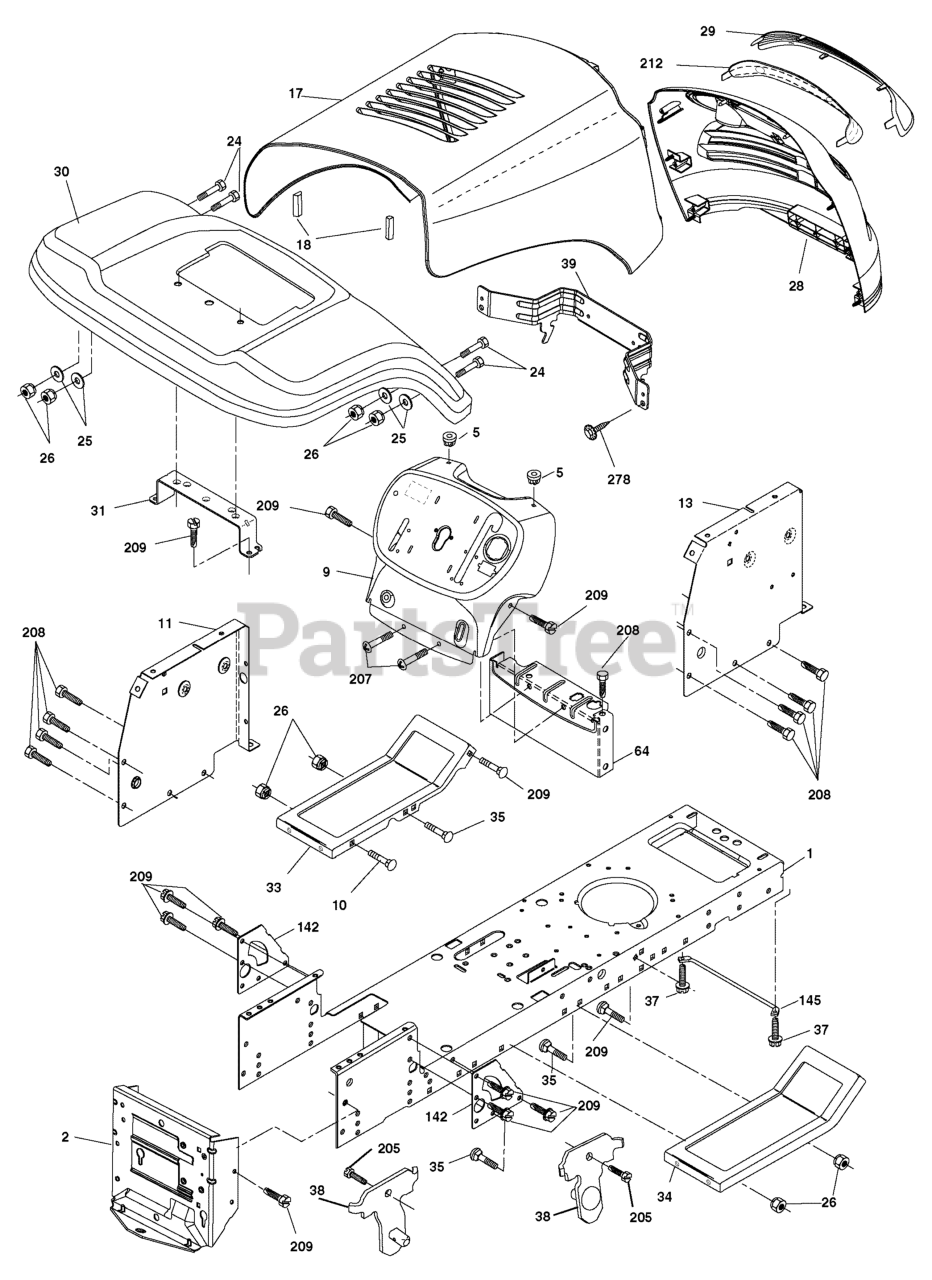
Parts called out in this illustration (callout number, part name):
1	CHASSIS
2	DRAWBAR
5	BUMPER, Hood / Dash
10	BOLT, Carriage, 3/8-16 x 1
11	PANEL, Dash, L.H.
13	PANEL, Dash, R.H.
17	** HOOD ASSEMBLY
18	BUMPER, Hood Large 1.75
24	BOLT, Fin Hex 3/8-16 unc x 1 Gr. 5
25	WASHER, 13/32 x 13/16 x 12 Ga.
28	** GRILLE
30	** FENDER
31	BRACKET, Fender Support
33	** FOOTREST, LH
34	** FOOTREST, RH
35	BOLT, Carriage, Short Neck 3/8-16 x 3/4
37	SCREW, Thdrol 5/16-18 x 1/2 Tyt
38	BRACKET ASSEMBLY, Pivot Mower Rear
39	BRACKET, Pivot
64	DASH, Lower STLT
142	PLATE, Reinforcement STLT
145	ROD, Pivot Chassis/Hood
205	SCREW, Thdrol 3/8-16 x 1/2
207	SCREW, Thdrol 5/16-18 x 1/2 TYTT
208	SCREW, Thdrol 3/8-16 x 1/2
209	SCREW, Hex Wsh Thdr 3/8-16 x 3/4
212	INSERT, Lens Reflective
278	SCREW, #10 x .750 BOS Thread
